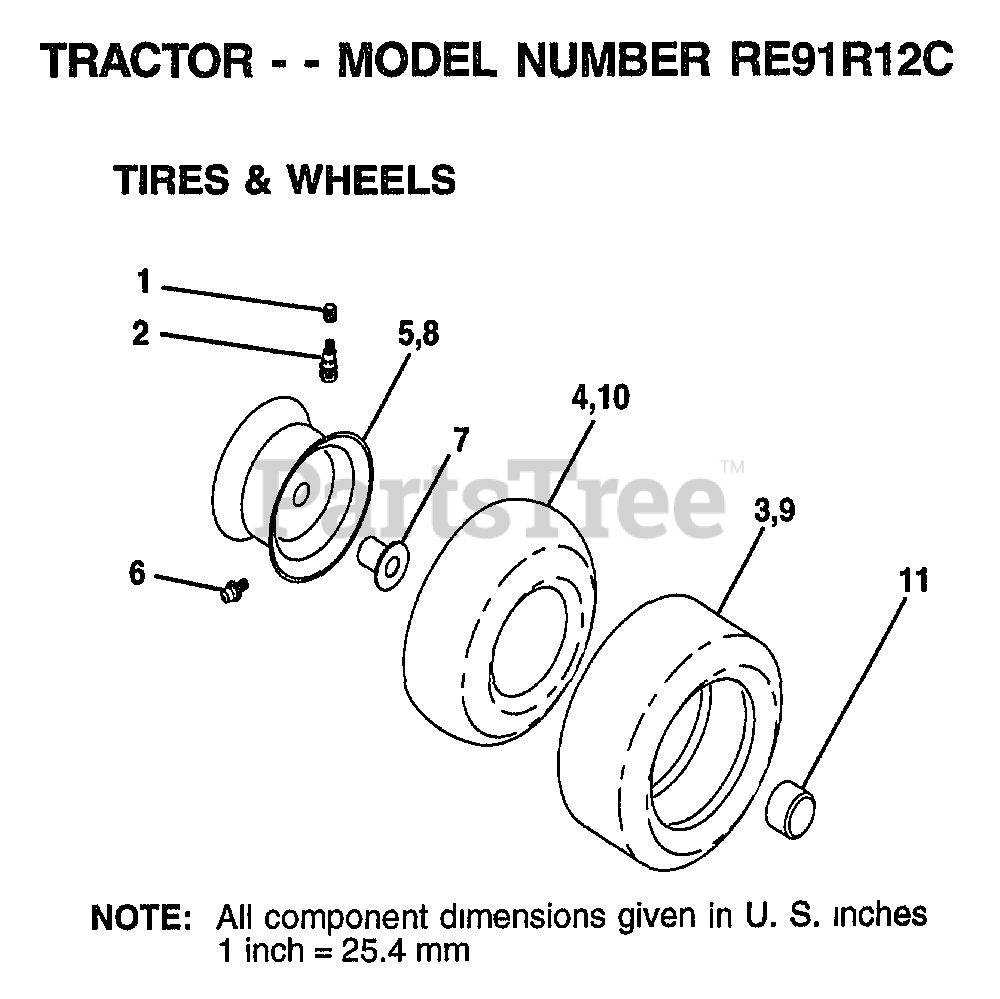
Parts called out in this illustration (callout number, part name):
1	VALVE CAP
2	VALVE STEM LT
3	FITTING LT
5	TUBE.5.3/4.5/6
5	TUBE.16X6.5/7.5-8
6	"RIM FRONT 6"""
6	"RIM ASM REAR 8"""
7	HUB CAP
8	"FLANGE, BEARING"
9	WASHER
